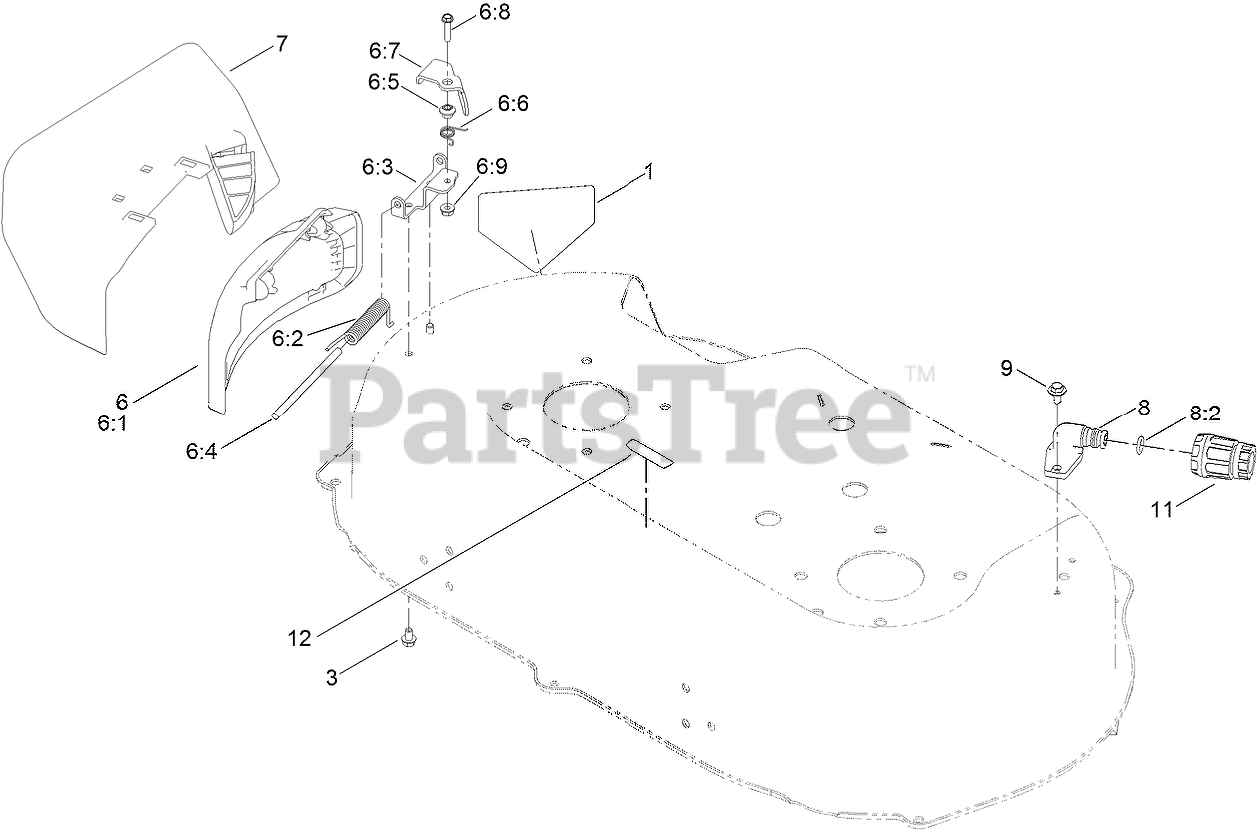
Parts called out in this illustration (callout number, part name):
1	DECAL-DANGER
6	SIDE DEFLECTOR SERVICE ASM
6:1	DEFLECTOR-DISCHARGE, SIDE
6:2	SPRING-TORSION, COVER
6:3	BRACKET-LOCKOUT
6:5	SPACER
6:6	SPRING-TORSION
6:7	LEVER-LOCKOUT
6:8	SCREW-HWH
6:9	NUT-LOCK, FLANGE
7	SIDE DISCHARGE CHUTE ASM
8	FITTING-WASHOUT
8:2	O-RING
9	SCREW-HWH, THD ROLL
11	CONNECTOR-HOSE
12	DECAL-WARNING
